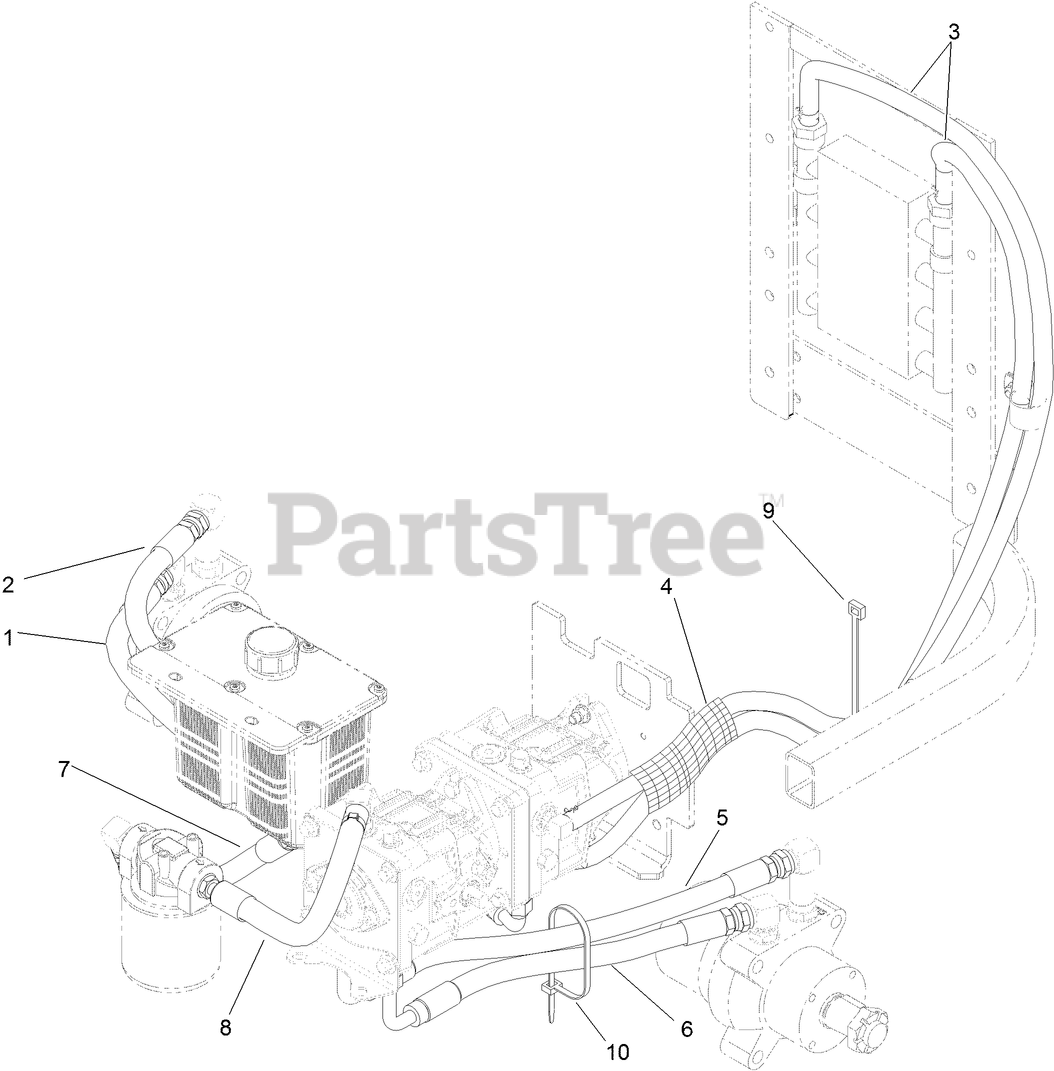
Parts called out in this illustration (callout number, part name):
1	HYDRAULIC HOSE ASM
2	HYDRAULIC HOSE ASM
3	HOSE-HYDRAULIC
4	SLEEVE-FABRIC
5	HYDRAULIC HOSE ASM
6	HYDRAULIC HOSE ASM
7	HYDRAULIC HOSE ASM
8	HYDRAULIC HOSE ASM
9	TIE-PLASTIC
10	CABLE TIE-PLASTIC
